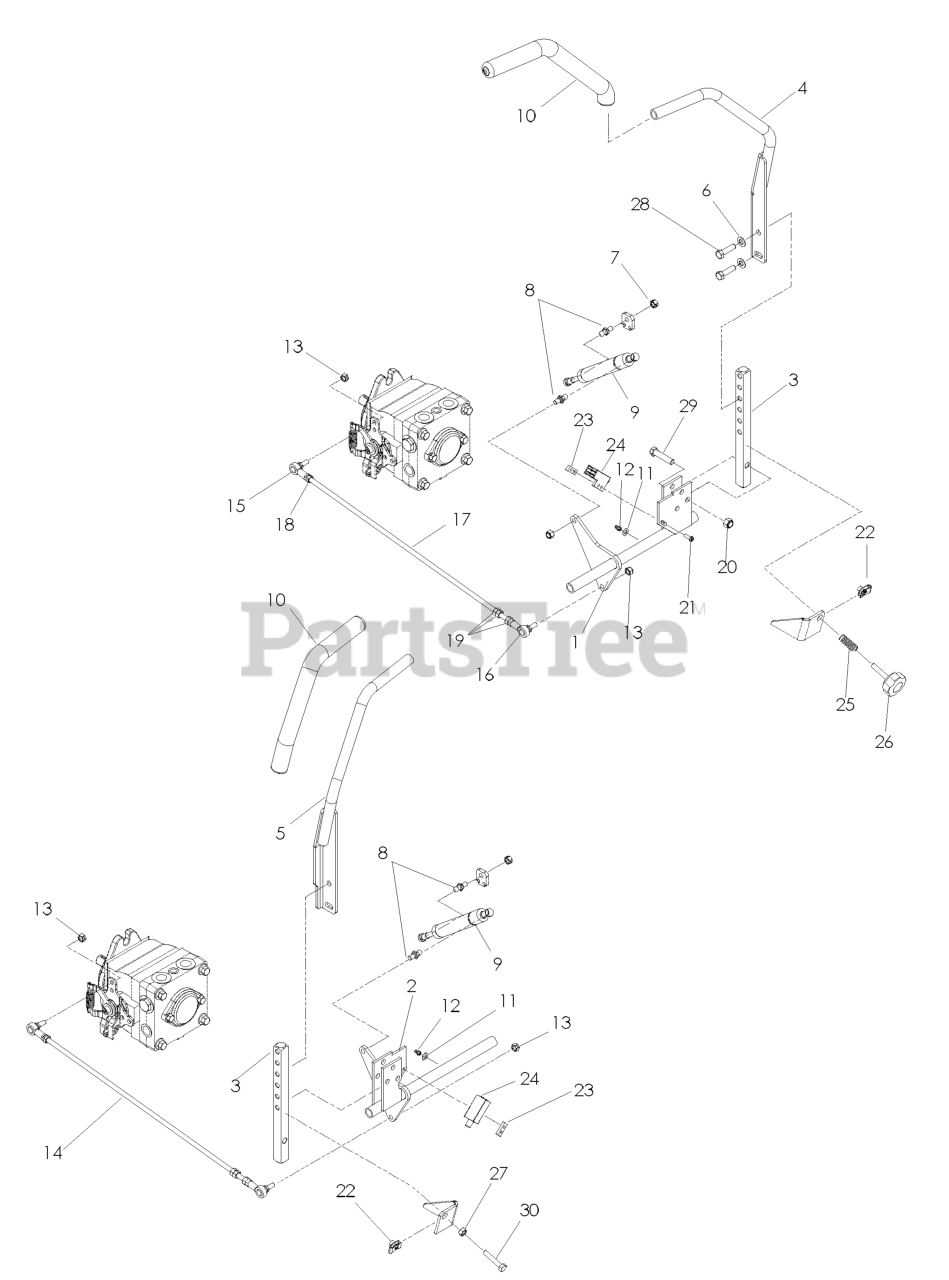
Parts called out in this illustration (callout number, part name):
1	CONTROL WLDMT, LT
2	CONTROL WLDMT, RT
3	CONTROL ARM
4	LT DRIVE LEVER WLDMT
5	RT DRIVE LEVER WLDMT
6	WASHER, 3/8 DISC SPRING SPEC
7	NUT 5/16C CENTERLOCK
8	STUD.BALL.10MM
9	DAMPENER W/EXT SEAL
12	ZERK
13	NUT 5/16F NYLOC
15	SPHERICAL ROD END, LH
16	SPHERICAL ROD END, RH
18	NUT 5/16F LEFTHAND
20	NUT 3/8-16 NYLOC
21	SCREW #10-24 X 5/8
22	U-CLIP 5/16-18 NUT RETAINER
23	TAPPED PLATE
25	COMPRESSION SPRING
26	ADJUSTMENT KNOB
27	NUT 5/16C HEX
28	HCS 3/8-16X1.GRD.5.ZD
29	HCS 3/8-16 X 1 3/4 GR5
30	HCS 5/16-18X1-3/4 TPBLT
